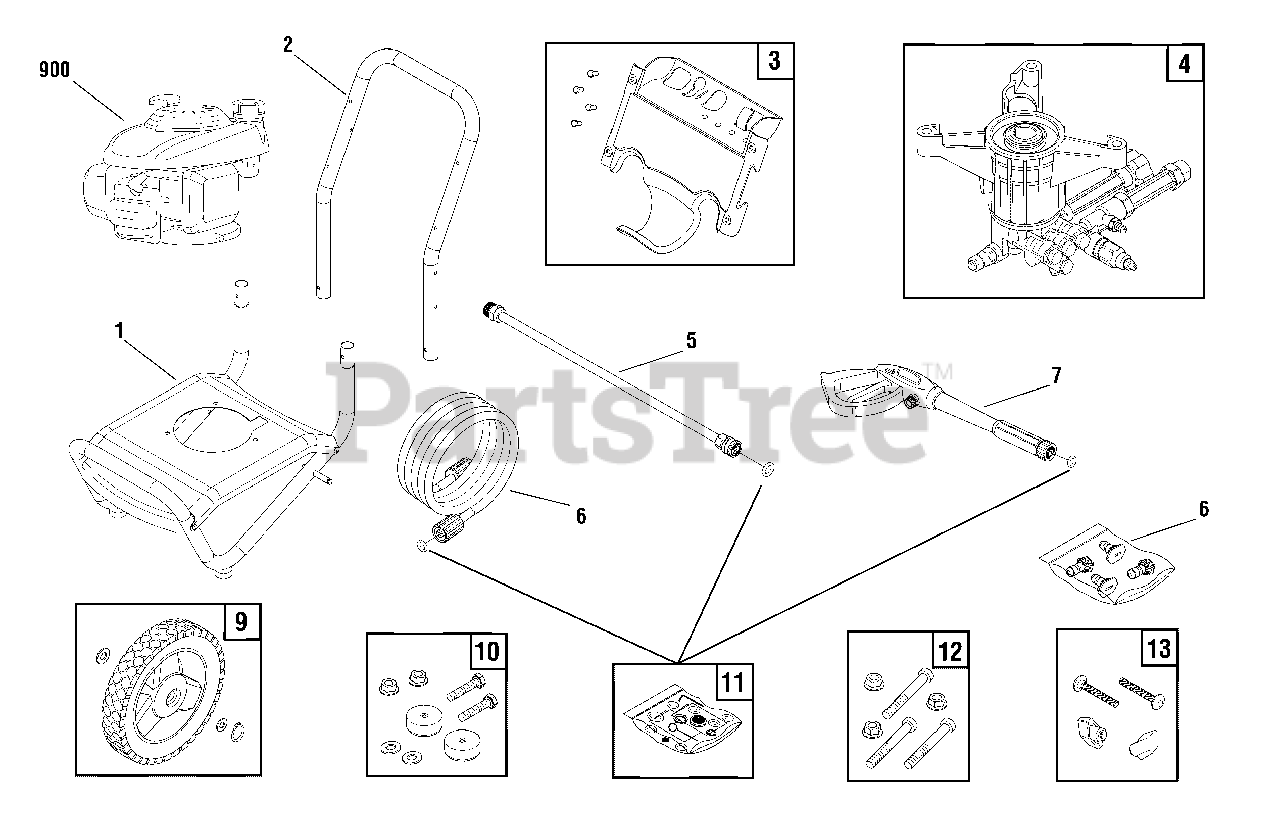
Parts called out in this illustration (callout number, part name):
6	KIT-QC NOZZLES
7	GUN
8	HOSE
10	MOUNT-VIBRATION
12	KIT-HARDWARE PUMP MOUNTING
13	KIT-HARDWARE HANDLE
900	ENGINE
